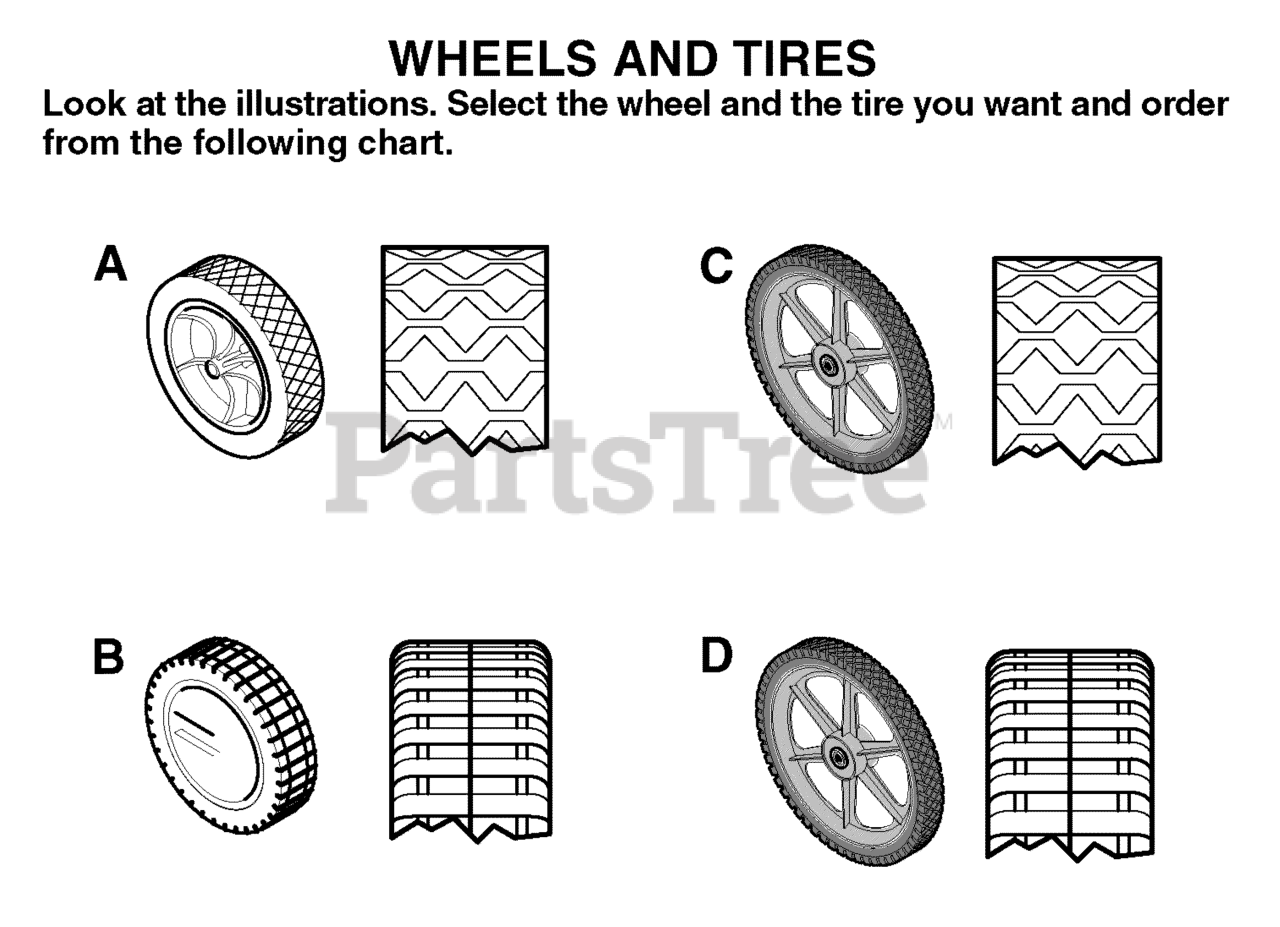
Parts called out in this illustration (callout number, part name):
1	6-inch Plastic, White (a)
2	6-inch Plastic, Gray (a)
3	7-inch Plastic, White (a)
4	7-inch Plastic, Gray (a)
5	8-inch Plastic, White (a)
6	8-inch Plastic, Gray (a)
7	8-inch Plastic, Gray (b)
8	8-inch Metal, White (a)
9	8-inch Ball Bearing, Gray (b)
10	14-inch, Gray (c)
11	14-inch, Gray (d)
12	14-in, Ball Bearing, Gray (c)
13	14-in, Ball Bearing, Gray (d)
